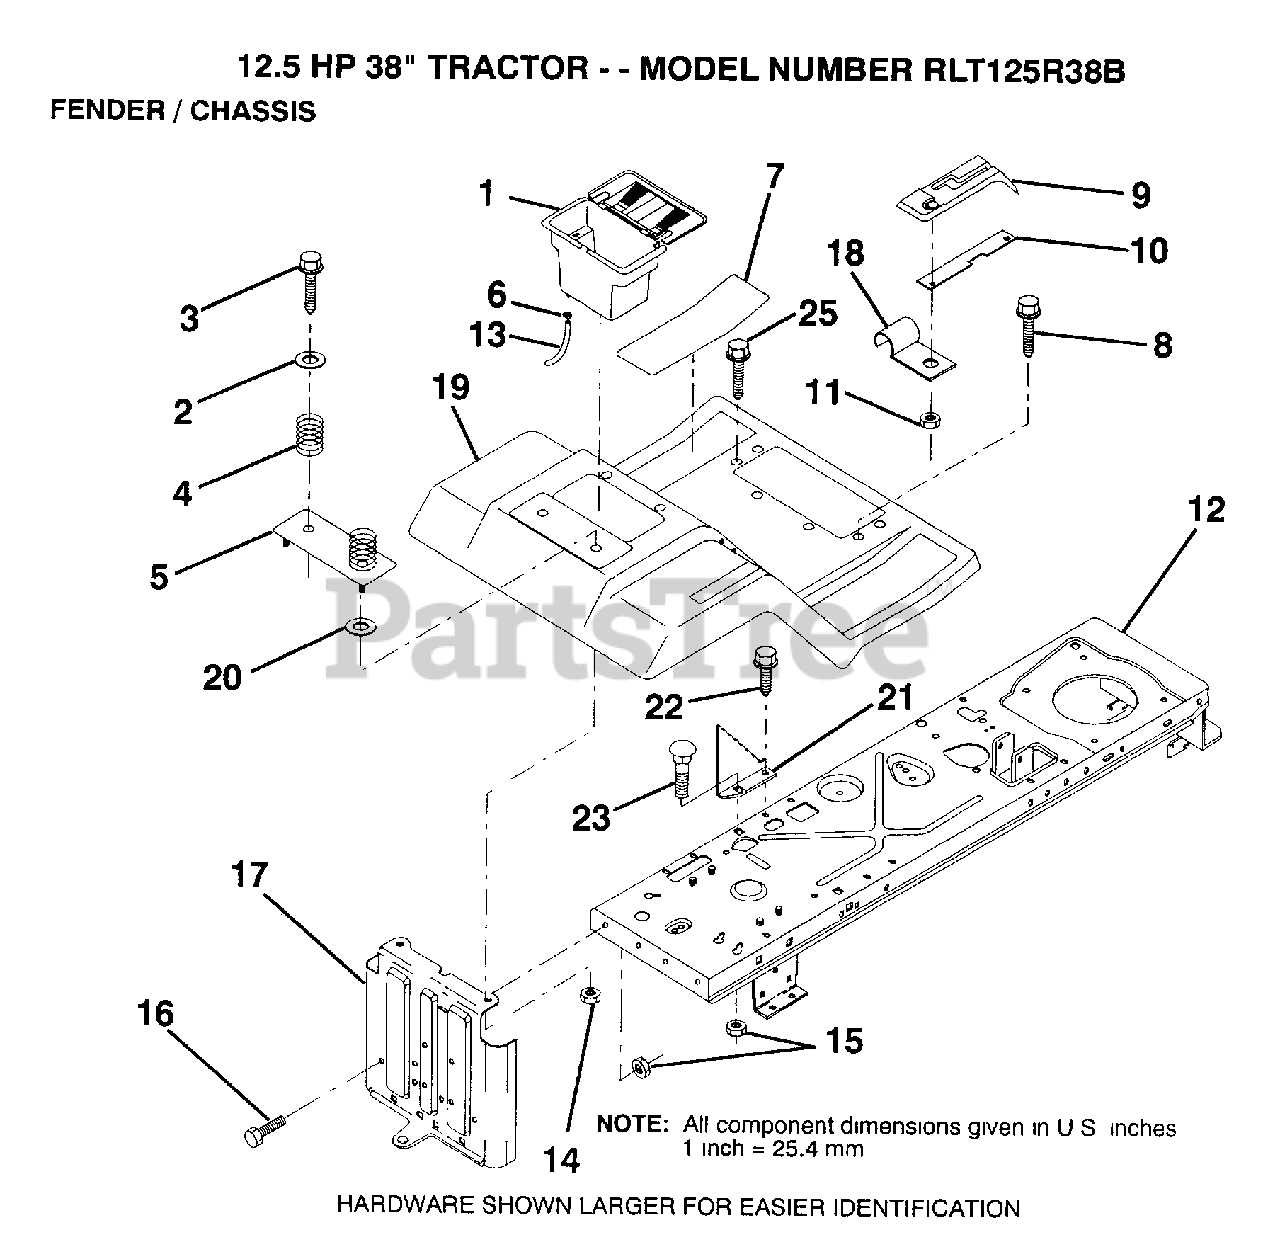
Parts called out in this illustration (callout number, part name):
2	WASHER
3	SCREW
4	SPRING COMPRESSIO
5	"PLATE, BATTERY"
6	HOSE CLAMP T
7	PAD FOOTREST
8	SCREW
10	"SHIFT LOCK, BAR"
11	NUT
13	TUBE T
14	NUT
16	BOLT
17	DRAWBAR
18	"CLIP,INSULATOR"
22	SCREW LT
25	SCREW TI
